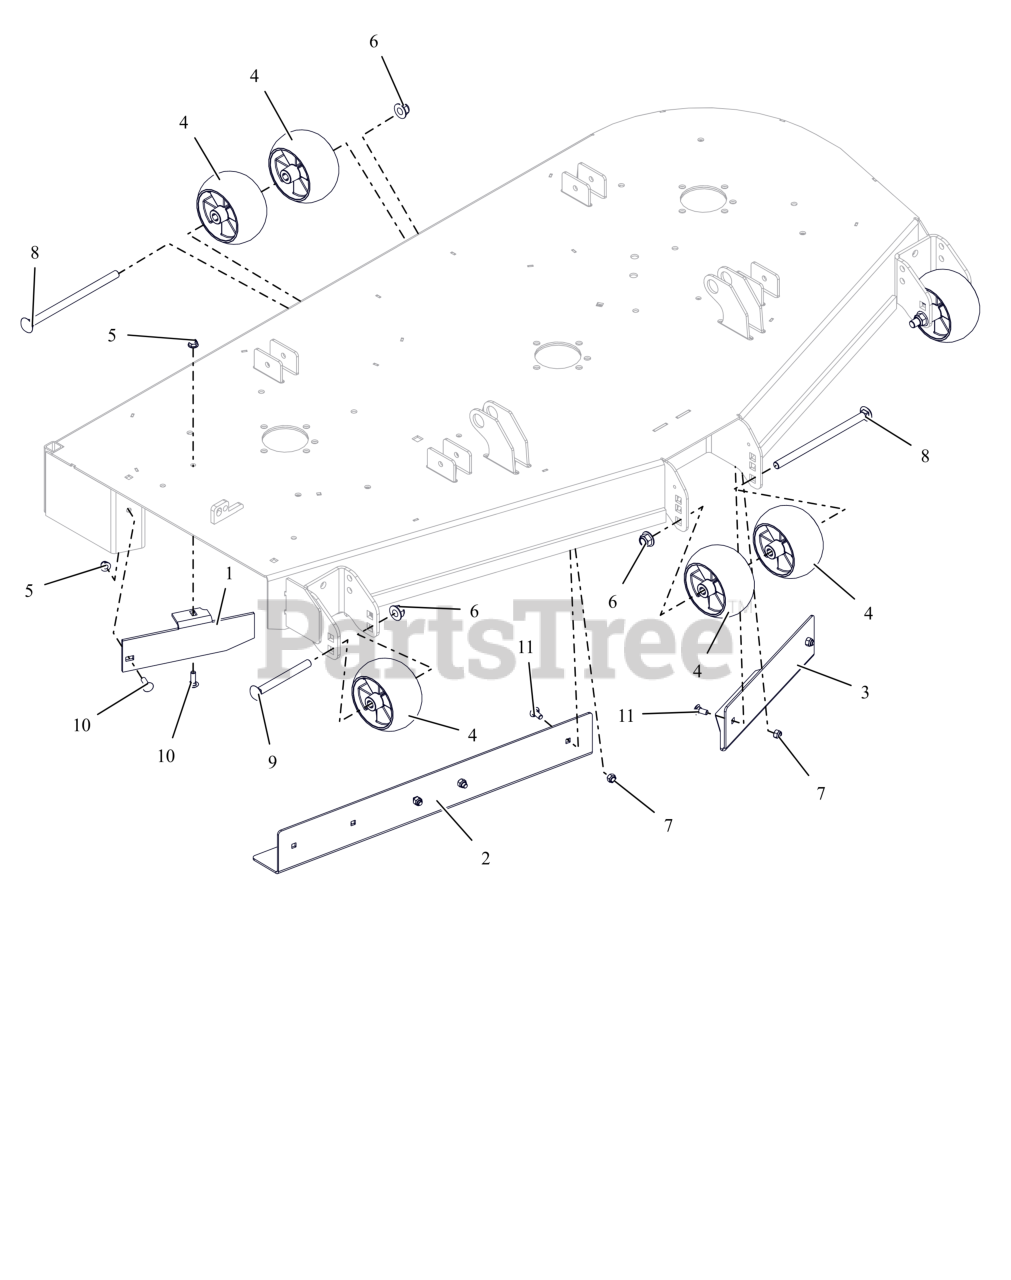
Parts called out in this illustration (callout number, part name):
1	60" DISCHARGE BAFFLE - RED
2	BAFFLE, 60" RH VACUUM (RED)
3	BAFFLE, 60" LH VACUUM (RED)
4	WHEEL, ANTI SCALP - 5X3 CTR W/RIBS
5	NUT,NYL-FLG .31-18 GF ZCC
6	NUT,NYL-FLG .50-13 GF ZCC
7	NUT,NYL .31-18 G5 ZCC
8	BTL,RHSN .500-13 X 8.5S G5 ZCC
9	BLT, RHSN .50-13X5.00 G5 ZCC
10	BLT,RHSN .31-18X1.00 G5 ZCC
11	BLT,RHSN .31-18X.75 G5 ZCC
